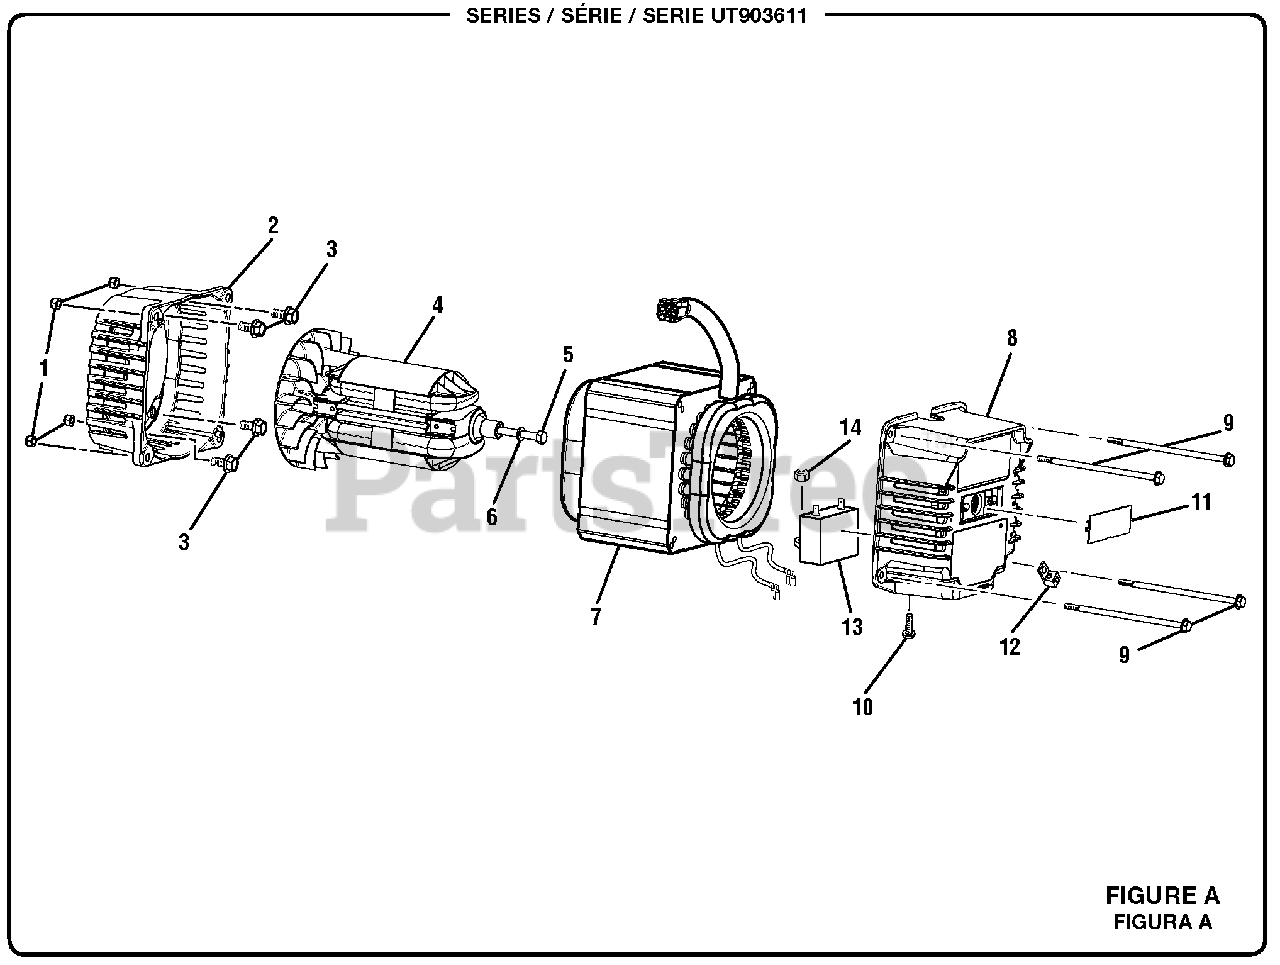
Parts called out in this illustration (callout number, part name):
1	Lock Nut (1/4-20)
2	Engine Adapter
3	Bolt (5/16-24 x 5/8 in.)
5	Bolt (5/16-24 x 7-3/4 in., Hex Hd.)
6	Lock Washer (5/16 in.)
9	Bolt (1/4-20 x 5-1/2 in. Hex Hd.)
10	Bolt (M5 x 16 mm, Pan Hd.)
11	Brush Cover
12	Ground Lug
13	Capacitor
14	Hex Nut (M5)
